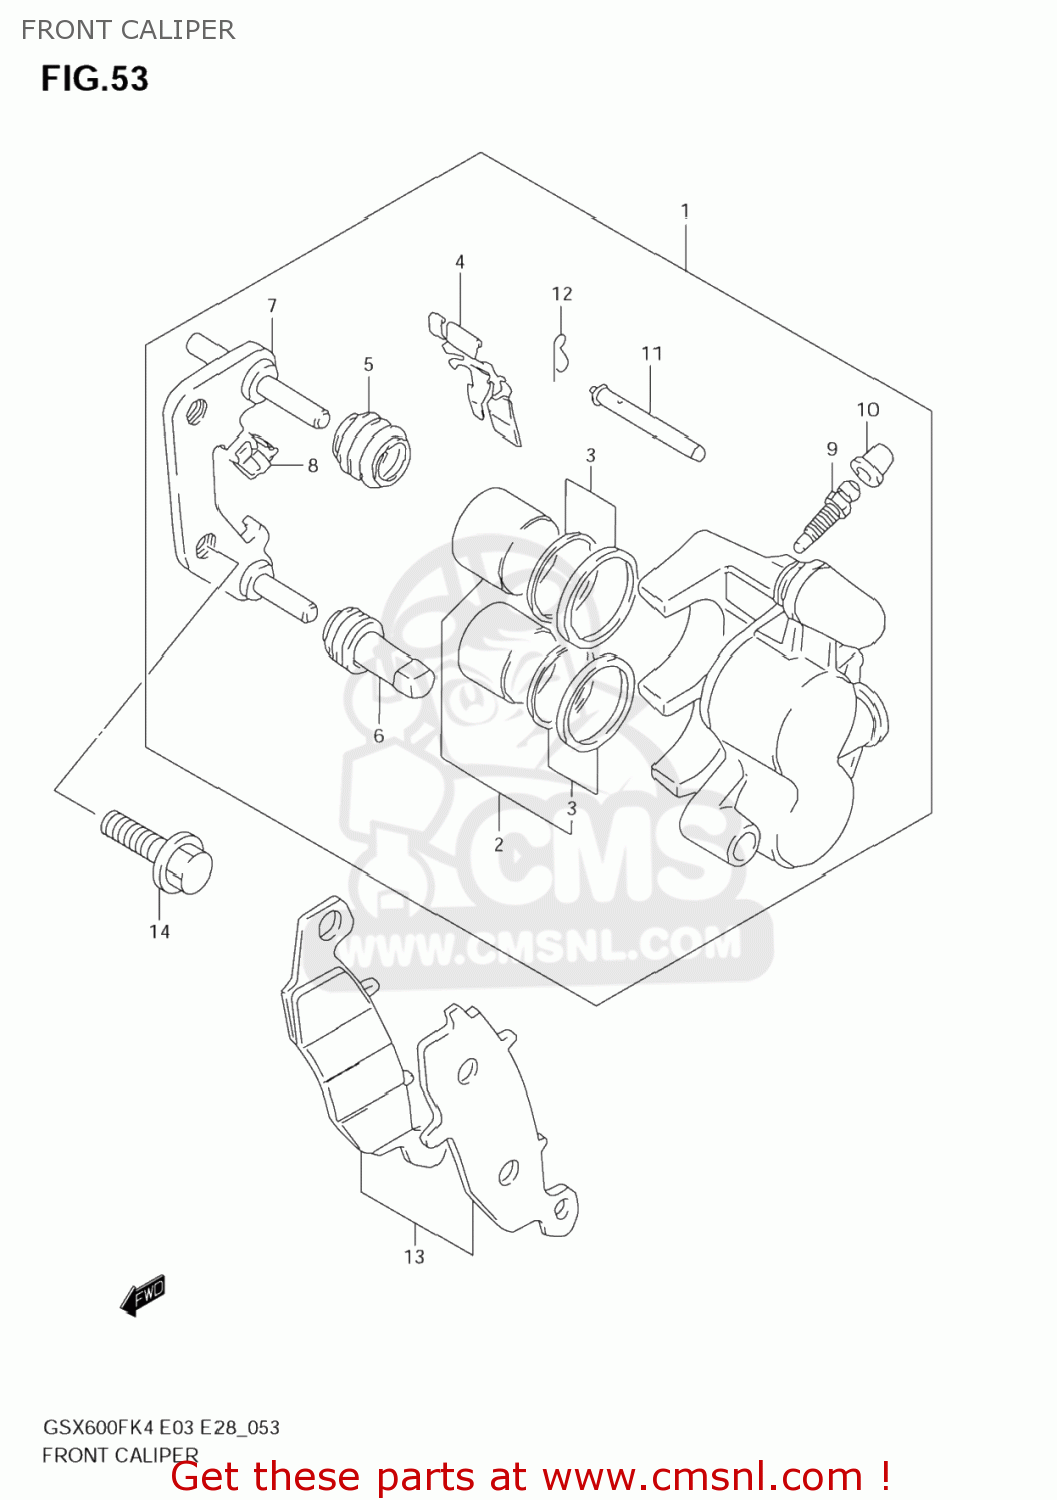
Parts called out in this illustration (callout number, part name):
1	CALIPER ASSY, FRONT RH
2	PISTON SET
3	SEAL SET,PISTON
4	SPRING,PAD,R
5	BOOT,AXLE
6	INSULATOR,AXLE
7	CARRIER,CALIPER,R
8	GUIDE,PAD
9	BLEEDER
10	CAP,BLEEDER PLUG
11	PIN,PAD
12	CLIP,PAD PIN
13	PAD SET,R (NAS)
14	BOLT
